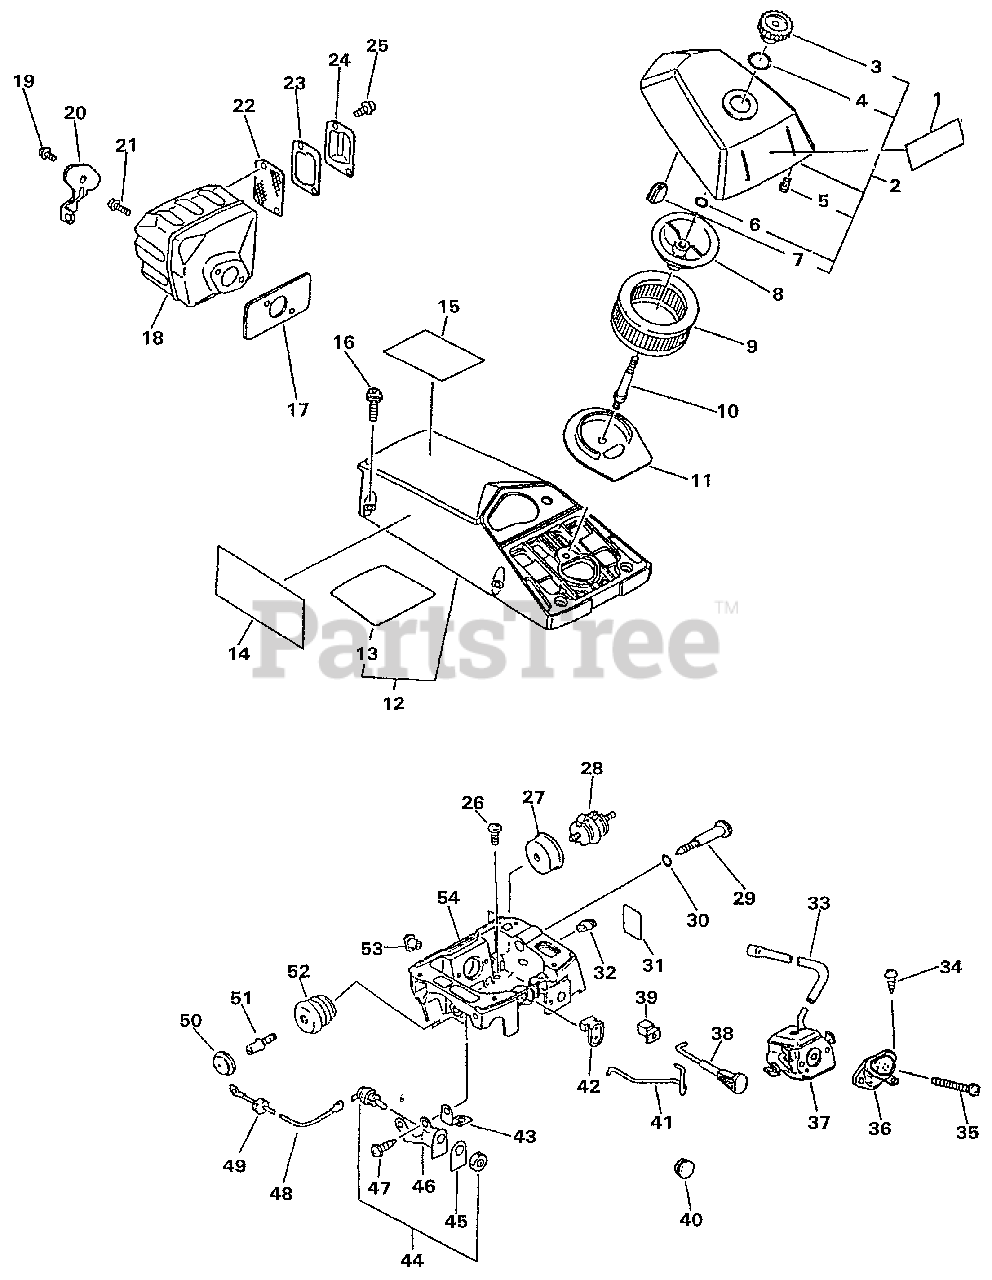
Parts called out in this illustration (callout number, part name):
1	LABEL - MODEL
2	AIR FILTER COVER ASSY
3	THUMBNUT
4	O-RING - 21
6	O-RING - 11
8	BRACKET, AIR CLEANER
9	FILTER, AIR
10	STUD
11	BRACKET, AIR CLEANER
12	COVER, ENGINE
13	COVER, ENGINE
14	LABEL - BAR & CHAIN
15	LABEL - KICK BACK
16	SCREW - 5X18
17	GASKET, EXHAUST
18	MUFFLER
19	SCREW - 5X10
20	BRACKET, MUFFLER
21	SCREW - 5X20
22	SCREEN, SPARK ARRESTOR
23	GASKET, EXHAUST
24	LID, MUFFLER
25	SCREW - 4X10
26	SCREW - 5X18
27	PLATE, CUSHION
28	CUSHION
29	KNOB, CARBURETOR ADJUST
30	O-RING - 6
31	LABEL - IDLE
33	PIPE - IMPULSE
34	SCREW - 5X14
35	SCREW - 5X50
36	ADAPTOR, INTAKE
37	CARBURETOR HDA-82
38	ROD, CHOKE
39	GROMMET
41	ROD, THROTTLE
42	GUIDE, THROTTLE ROD
43	TERMINAL - GROUND
44	IGNITION SWITCH ASSY
45	LABEL - SWITCH
46	BRACKET, SWITCH
47	SCREW - 5X10
48	LEAD - GROUND
50	CAP, CUSHION
52	CUSHION
54	CASE, CARBURETOR
